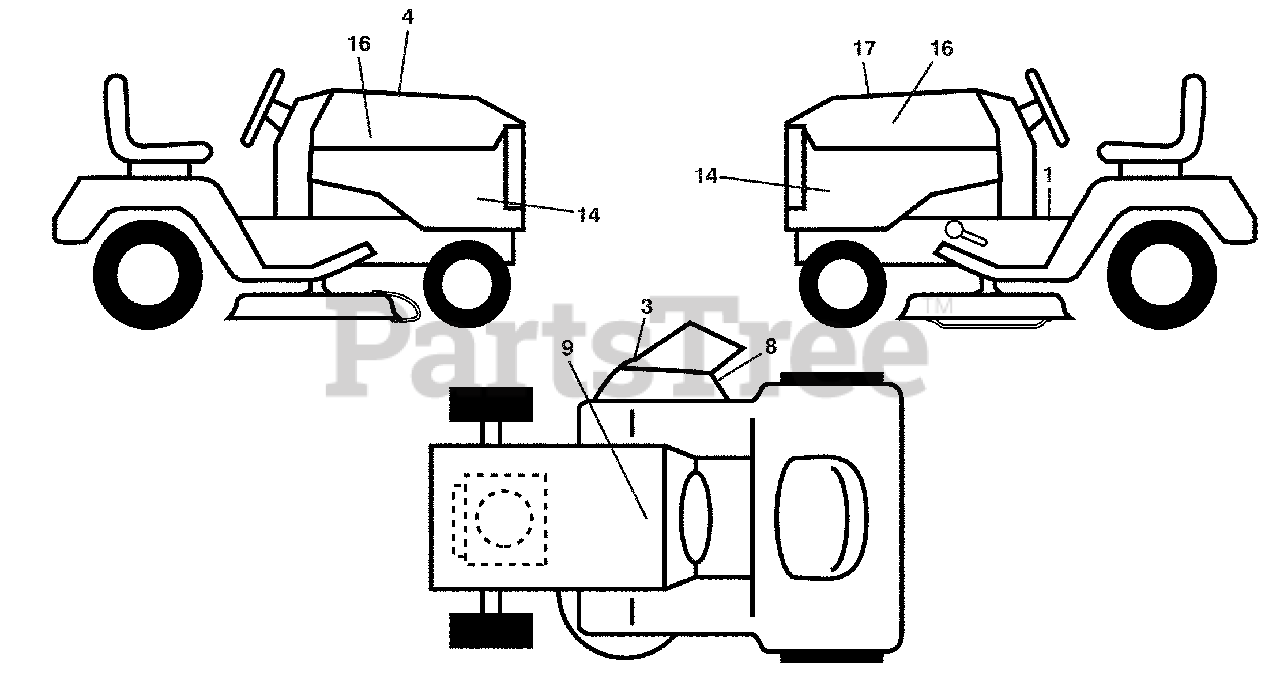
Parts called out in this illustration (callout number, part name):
1	Decal, Fender Warning
3	Decal, Warning
4	Decal, Hood Cust Resp
8	Decal, Mower Sch.
9	Decal, Battery Dnge/Poi
14	Decal, Panel Side
16	Decal, Hood Logo
17	Decal, Replacement
18	Decal, Bypass
19	Pad, Footrest, LH
20	Pad, Footrest, RH
